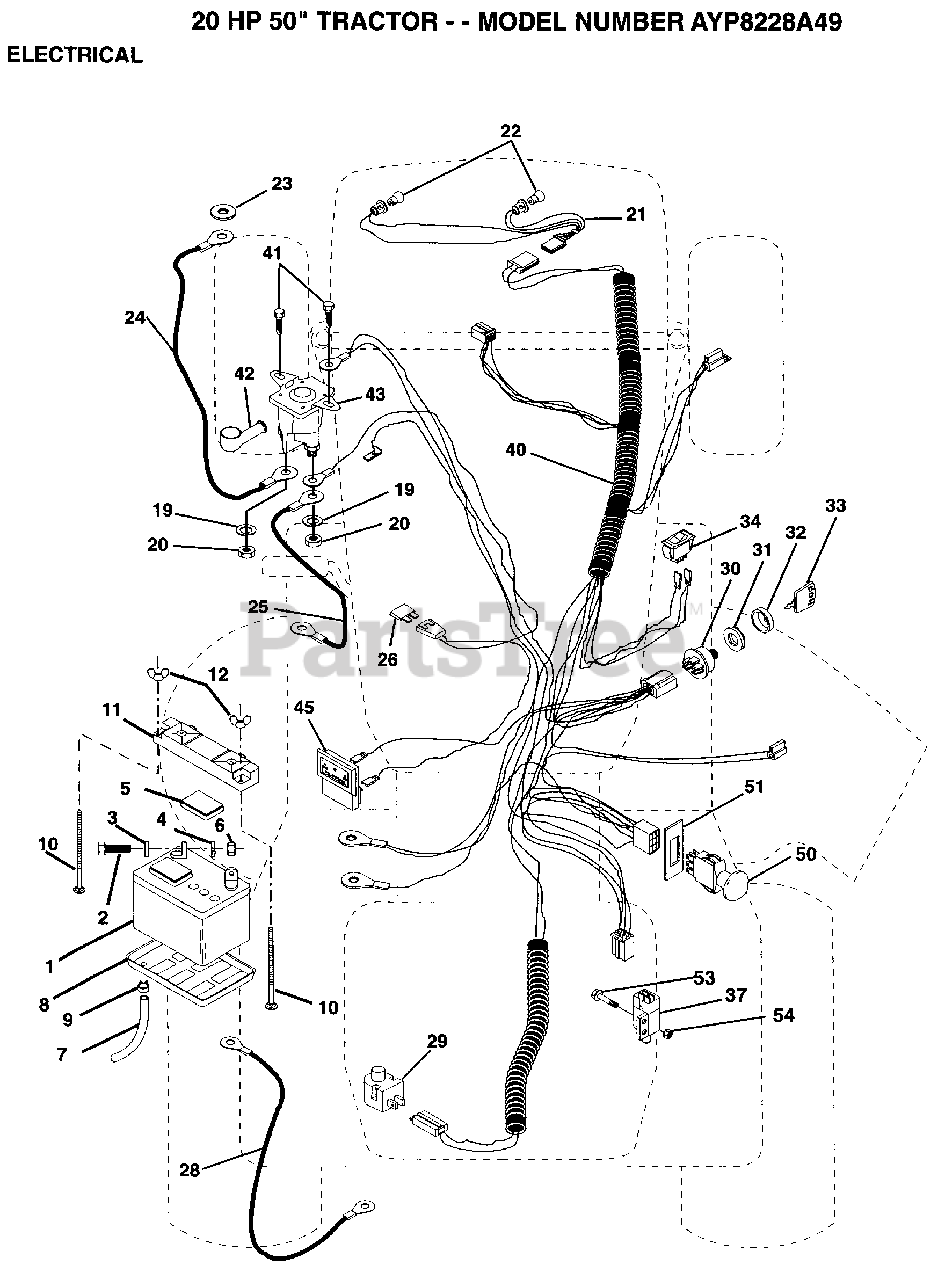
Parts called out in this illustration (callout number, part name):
2	BOLT LT
3	LOCKWASHER
4	WASHER
5	"CAP,BATTERY "
7	"DRAIN TU T, BATT"
8	"TRAY T, BATTERY"
9	HOSE CLAMP T
10	BOLT
20	NUT
22	HEADLAMP BULB
23	LOCKWASHER
24	"CABLE T, BATTERY"
25	CABLE-BATTERY T
26	FUSE HYT
28	CABLE T
29	SWITCH SEAT
32	COVER KEY SWITCH
33	KEY MLD GEN DELTA
34	SWITCH LT
37	SWITCH INTERLOCKT
40	HARNESS IGN GT
41	SCREW
45	AMMETER
51	RING RETAIN PTO
53	SCREW
54	"NUT,KEPS"
